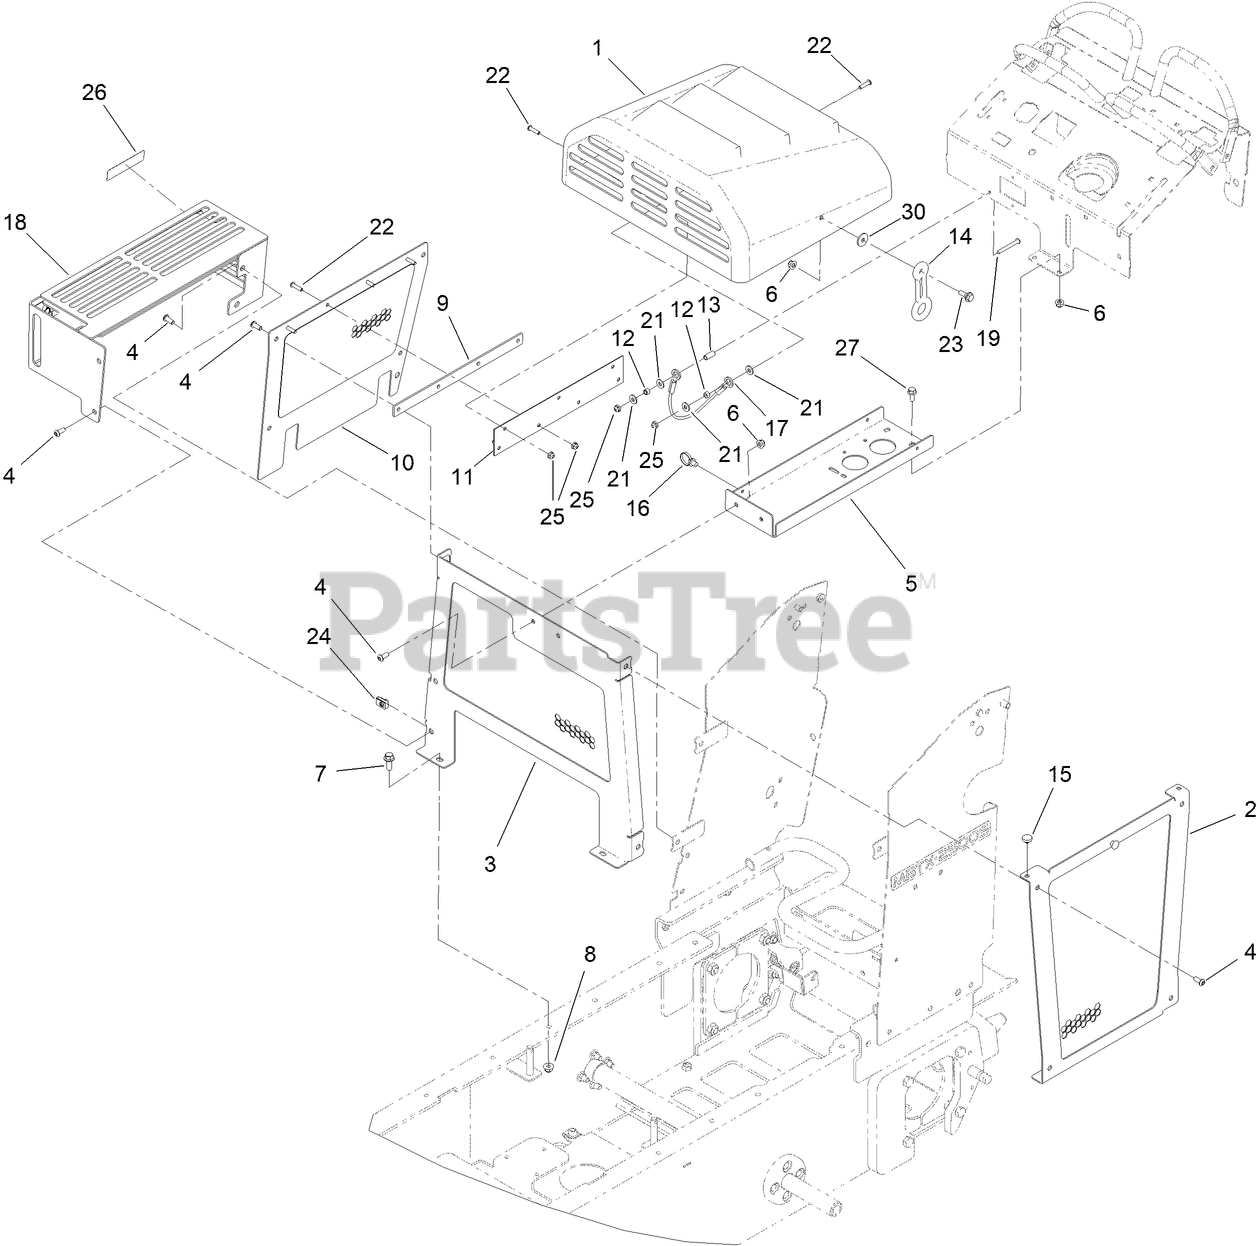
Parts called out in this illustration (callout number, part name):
1	HOOD ASM
2	PANEL-SIDE, LH
3	PANEL-FRONT (WELDED)
4	SCREW-HSBH
5	PLATFORM-BATTERY
6	NUT-HF, NI
7	SCREW-HHF
8	NUT-HF, NI
9	PLATE-SPACER, HOOD
10	PANEL-SIDE, UPPER
11	HINGE-HOOD
12	SPACER-BLADE, ROTOR
13	SPACER-BRAKE, PARKING
14	LATCH-RUBBER
15	BUMPER
16	CLIP-TIE
17	LANYARD
18	GUARD-MUFFLER
19	SCREW-HSBH
21	WASHER-FLAT
22	SCREW-HSBH
23	SCREW-SHOULDER
24	NUT-CLIP, U
25	NUT-HF
26	DECAL-ARRESTOR, SPARK
27	SCREW-HHF
30	WASHER-FLAT
